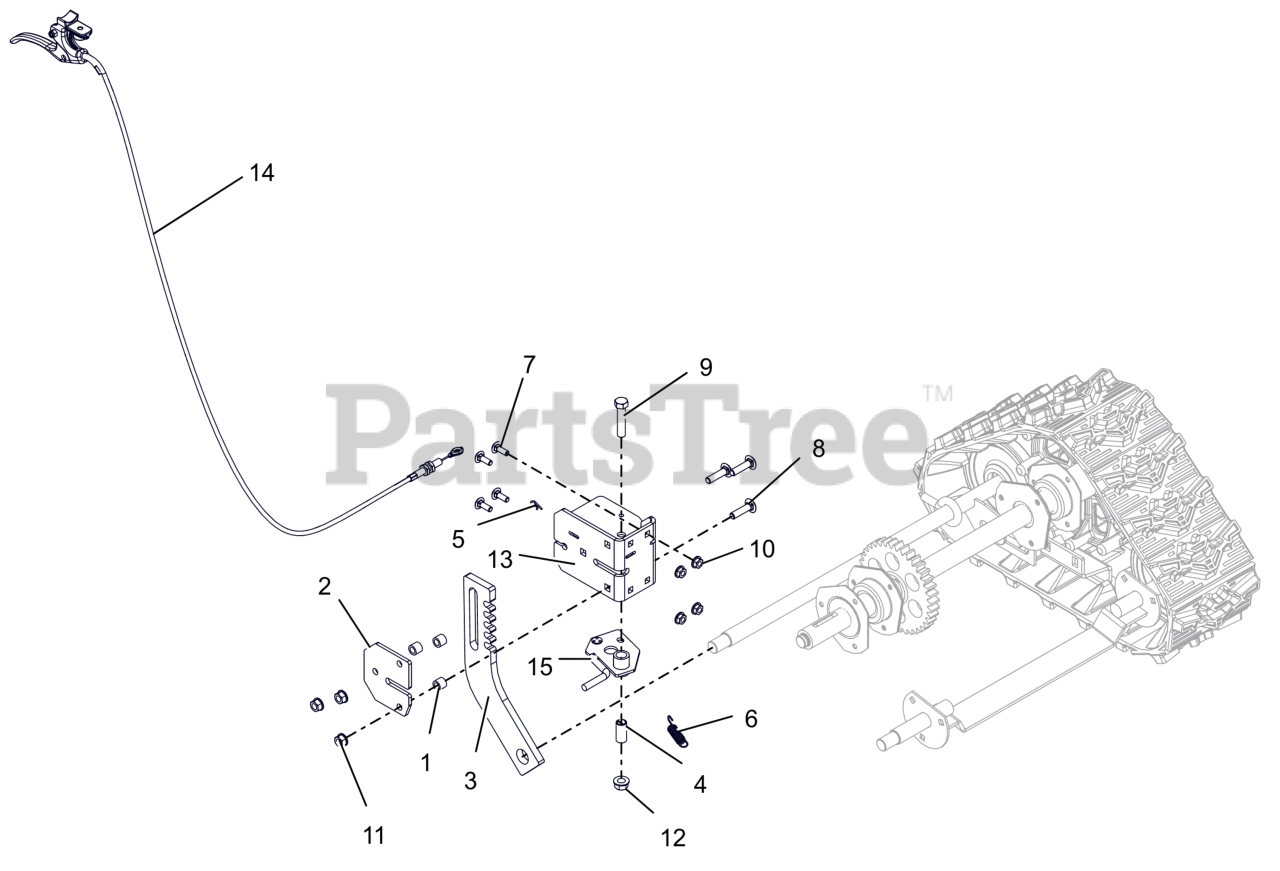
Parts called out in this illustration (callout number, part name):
1	SPACER .50 X .32 X .42
2	PLATE, HEIGHT ADJUSTER
3	STOP, HEIGHT ADJUSTER-CPT BLAC
4	BSHG-SLV .385X.500X1.045
5	PIN, HAIR #178 .06X.77 ZCC
6	SPRING-EXT .047 X .438 X 1.85
7	BLT, RHSN .25-20X.750 G5 ZCC
8	BLT, RHSSN.31-18X1.25 G5 ZCC
9	BLT, HEX .38-16X1.75 G5 ZCC
10	NUT-LK-CTR-FLG .25-20 ZC120
11	NUT-LK-TOP-FLG .312-18 GF ZCC
12	NUT-LK-CTR-FLG .375-16 GF ZCC
13	BRACKET, HEIGHT ADJUSTER
14	CABLE, TRACK REMOTE
15	LOCK,HEIGHT ADJUSTER TRIGGER
